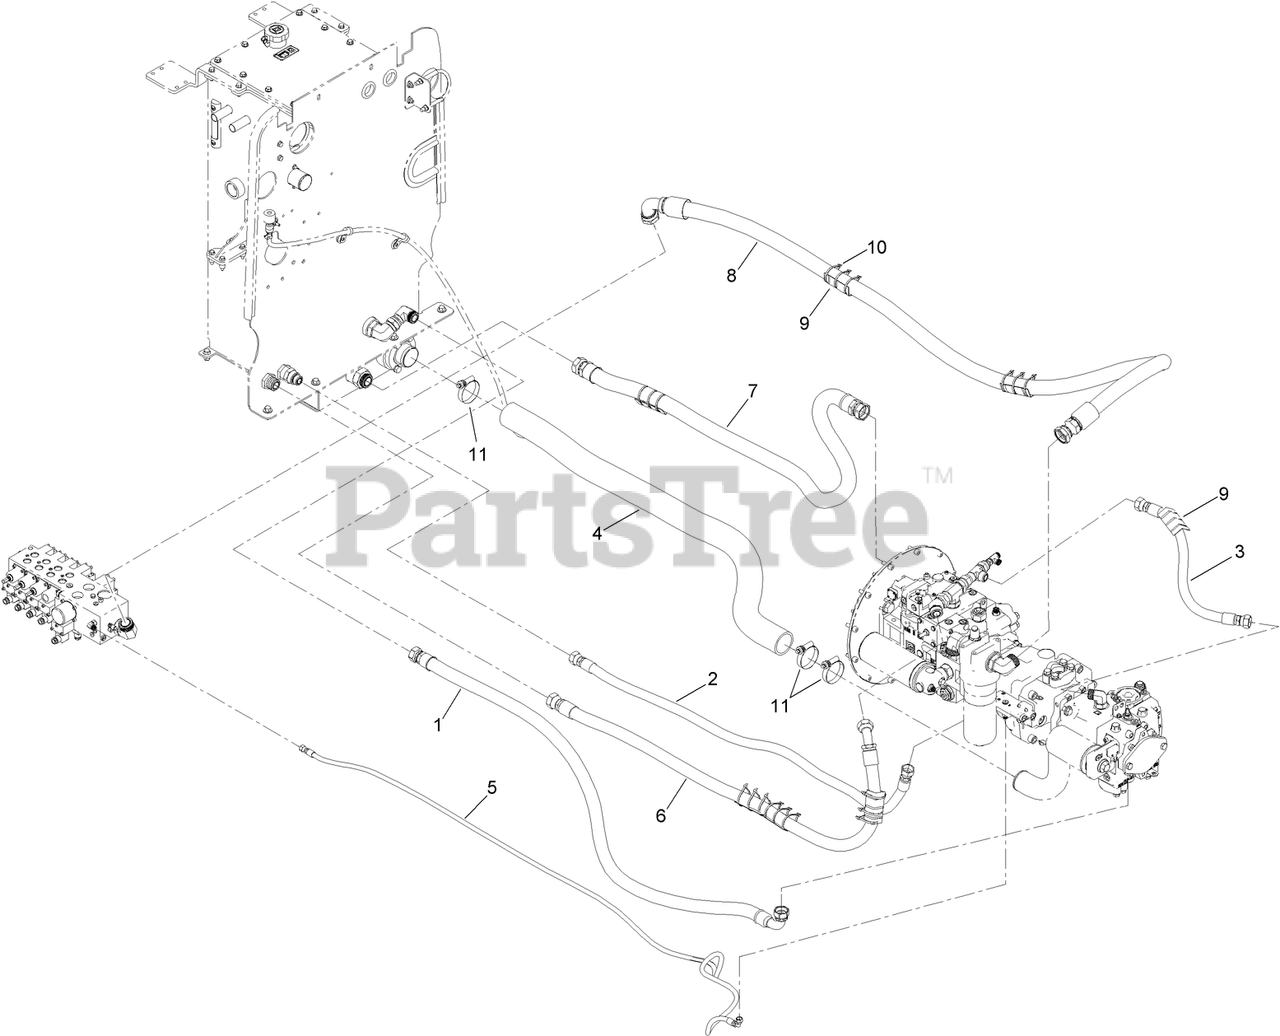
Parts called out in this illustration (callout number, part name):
1	HOSE ASM-HYD
2	HOSE ASM-HYD
3	HOSE ASM-HYD
4	HOSE-SUCTION
5	HOSE ASM-HYD
6	HOSE ASM-HYD
7	HOSE ASM-HYD
8	HOSE ASM-HYD
9	PROTECTOR-HOSE
10	TIE-CABLE
11	Clamp-Hose
